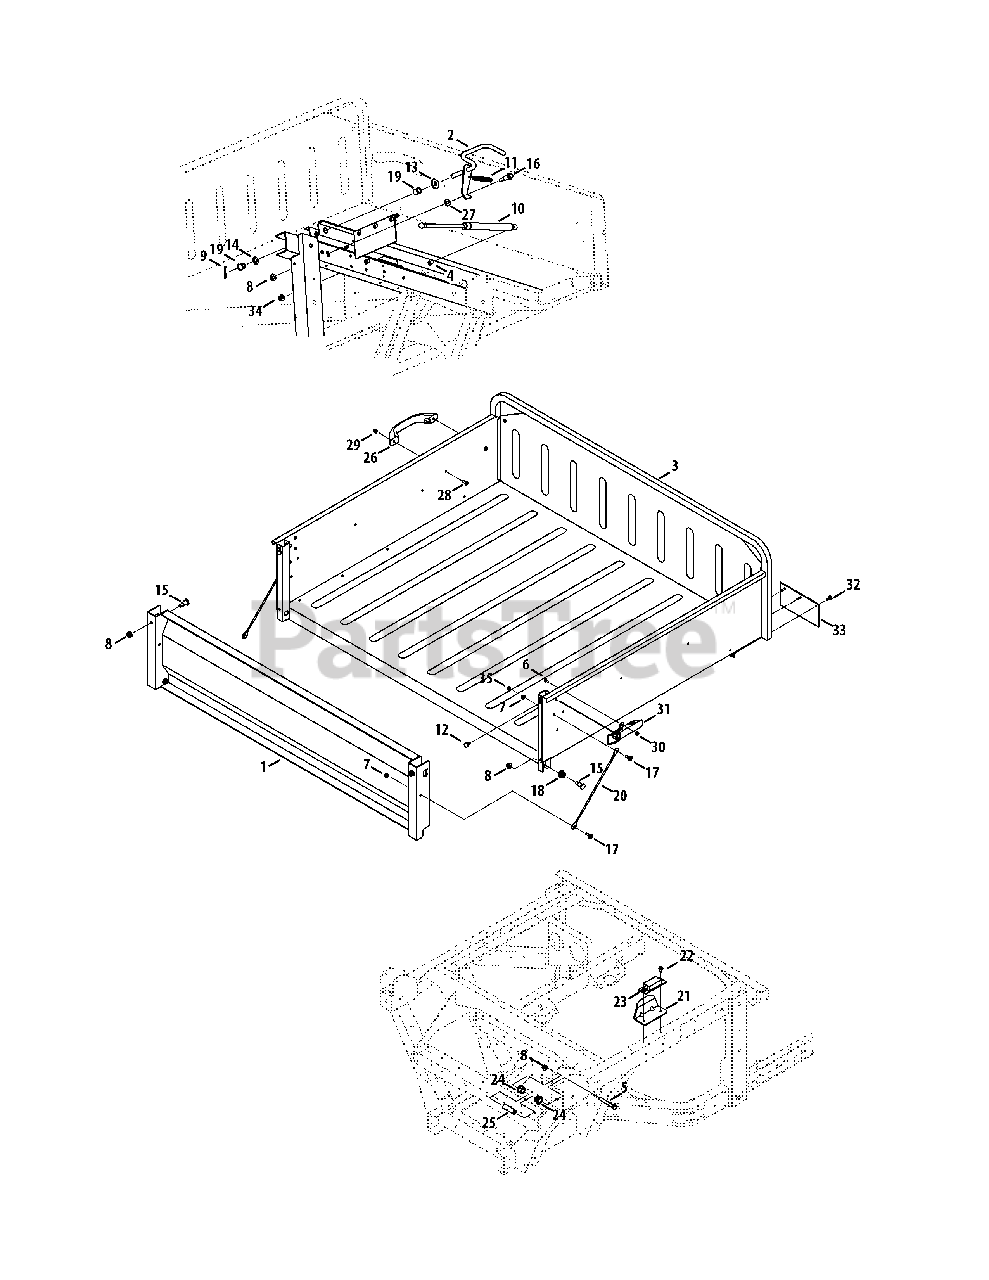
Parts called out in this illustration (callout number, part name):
1	Tailgate Assembly, Black
1	Tailgate Assembly, Cub Yellow
1	Tailgate Assembly, Green
1	Tailgate Assembly, Red
2	Lever Assembly, bed, latch
3	Box Assembly, bed Black
3	Box Assembly, bed Red
3	Box Assembly, bed Green
3	Box Assembly, bed Yellow
4	Stud, ball, 5/16-18
5	Screw, 3/8-16, 2.75, gr5, std
6	Screw, machine, 10-24, 0.500
7	Nut, Flange Lock, 1/4-20, nylon
8	Nut, Flange Lock, 3/8-16, nylon
9	Pin, cotter, 5/32, 1.25
10	Spring, gas, 6.91 Stroke
11	Spring, extension, .50 Od x 4.35
12	Bumper, .62 Dia. x .3
13	Washer, flat, .531 x 1.25 x .181
14	Washer, flat, .510 x 1.00 x .060
15	Screw, shoulder, .50 x .685, 3/8-16
16	Screw, shoulder, .50x.925, 3/8-16
17	Screw, shoulder, .375x.280, 1/4-20
18	Bearing, Flange, hex, .506 Id x .590
19	Bearing, Flange, .503 x .689 x .792
20	Cable, lanyard
22	Screw, tt, 1/4-20x.625, hxindwsh
23	Bumper, suspension, extension
24	Bearing, hex Flange .629 Id
25	Spacer, .390 Id x.625 Od x2.03 Lg
27	Washer, Flat, .385 x .870 x .092
28	Screw, Mach., 1/4-20 x .750
29	Nut, Hex Lock., 1/4-20
30	Nut, Hex lock, #10-24, gr2, nylon
31	Latch, draw, Over Center
32	Pop Rivet, .188 dia, 37-50 grip
33	Rear Mud Flap
34	Nut, Flange Lock, 5/16-18, nylon
35	Nut, Acorn, 1/4-20
